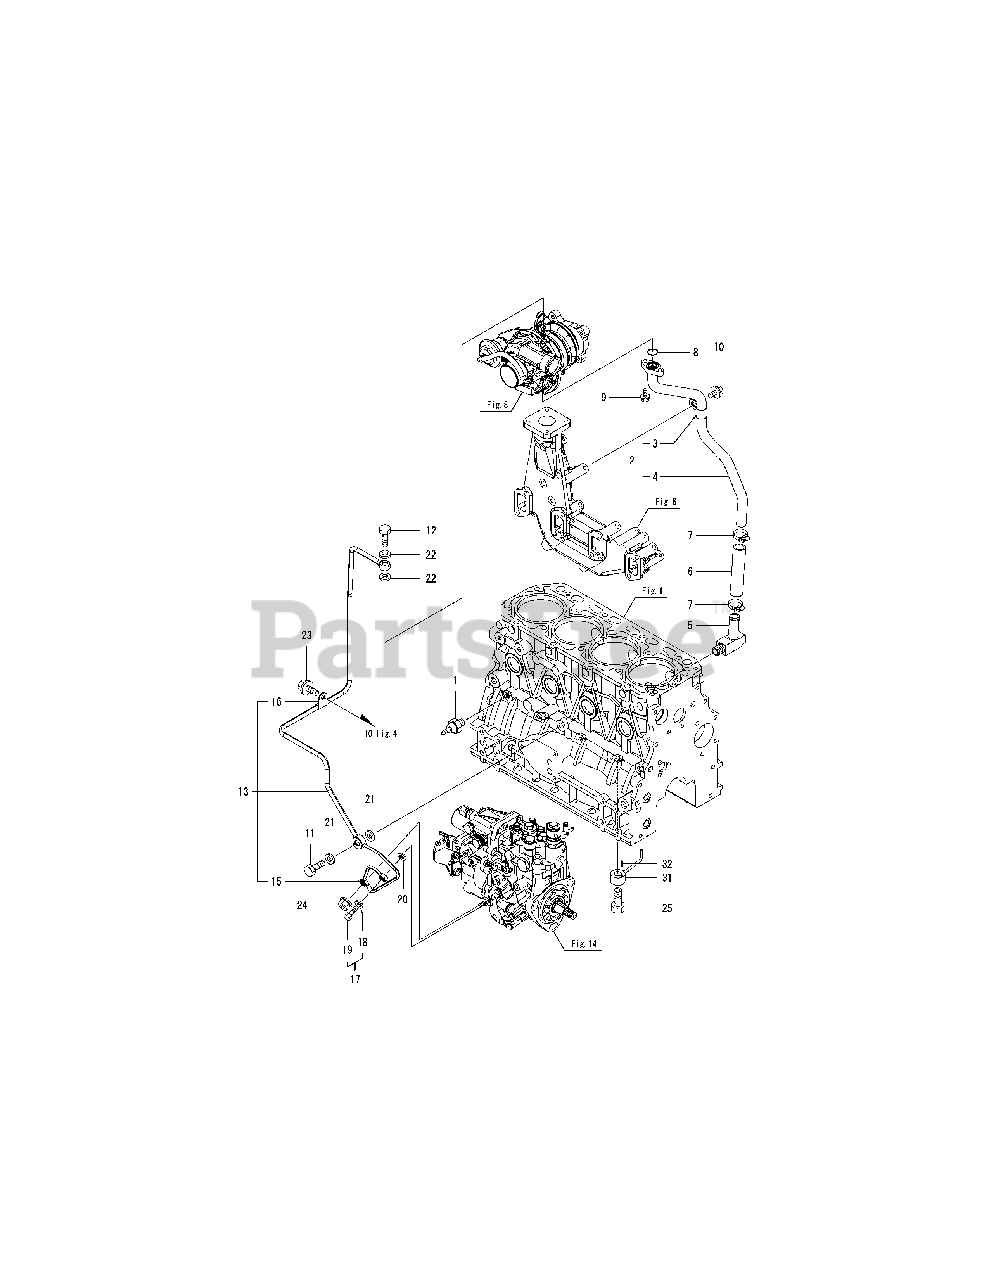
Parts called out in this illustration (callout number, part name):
1	SWITCH, OIL PRESSURE
2	PIPE ASSY, LO RETURN
4	LO-T,T/C RETURN
5	ELBOW,3/8 LO RETURN
8	O-RING 4D P-16.0
9	BOLT M 6X 12 PLATED
10	BOLT M 8X 12 PLATED
11	BOLT, JOINT M10
12	BOLT, PIPE JOINT
13	PIPE ASSY, LUB. OIL
15	RETAINER, PIPE
17	BOLT ASSY, JOINT
18	SEAL WASHER 8S
20	SEAL WASHER 8S
22	GASKET 10, ROUND
23	BOLT M 8X 12 PLATED
25	VALVE ASSY, CHECK
31	NOZZLE, COOLING
32	SPRING PIN 3X10
